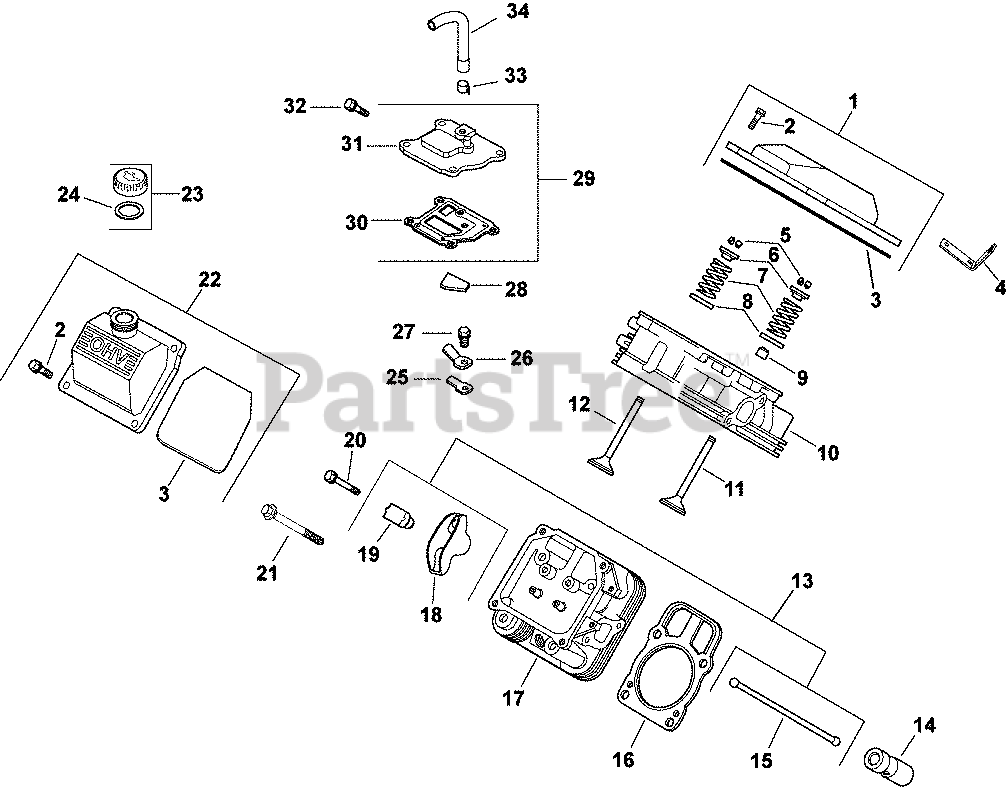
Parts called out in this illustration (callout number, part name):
1	KIT, VALVE COVER-PLAIN (PLASTIC)
2	SCREW, FLG M6X1.0X30
3	O-RING (YELLOW) -USE 24 153 30-S
4	STRAP, LIFTING-USE 25 445 03-S
5	KIT, RETAINER
6	RETAINER, VALVE SPRING - USE 25 173 28-S
7	SPRING, VALVE
8	RETAINER, SPRING
9	SEAL, VALVE STEM - (#2503214S)
10	HEAD, ASSEM CYLINDER #1 -USE 24 318 107-
11	VALVE, INTAKE (STD)
12	VALVE, EXHAUST (STD) - USE 32 016 01-S
13	KIT, VALVE TRAIN
14	LIFTER, HYDRAULIC VALVE-USE 25 351 10-S
15	ROD, PUSH
16	KIT, CYL HEAD GASKET (C17-22)
17	HEAD, ASSEM CYLINDER #2 -USE 24 318 115-
18	ARM, ROCKER
19	PIVOT, ROCKER ARM
20	SCREW, FLG M6X1.0X34
21	SCREW - USE 62 086 08-S
22	KIT, VALVE COVER-OIL FILL
23	KIT, OIL FILL CAP (BLACK)
24	O-RING, DIPSTICK
25	REED, BREATHER
26	RETAINER, REED
27	SCREW, FLG THD FRM M5X.8X10
28	FILTER, BREATHER-USE 24 050 11-S
29	KIT, BREATHER ASSEMBLY
30	GASKET, BREATHER-USE 24 041 67-S
31	COVER, BREATHER -USE 24 033 01-S
32	SCREW,FLG THD FRM M6X1.0X20-(#25086396S)
33	CLAMP, HOSE (KM)-USE 25 237 31-S
34	HOSE, BREATHER-USE 24 326 89-S
2401602-S	VALVE, EXHAUST (.25)
2401702-S	VALVE, INTAKE (.25)
